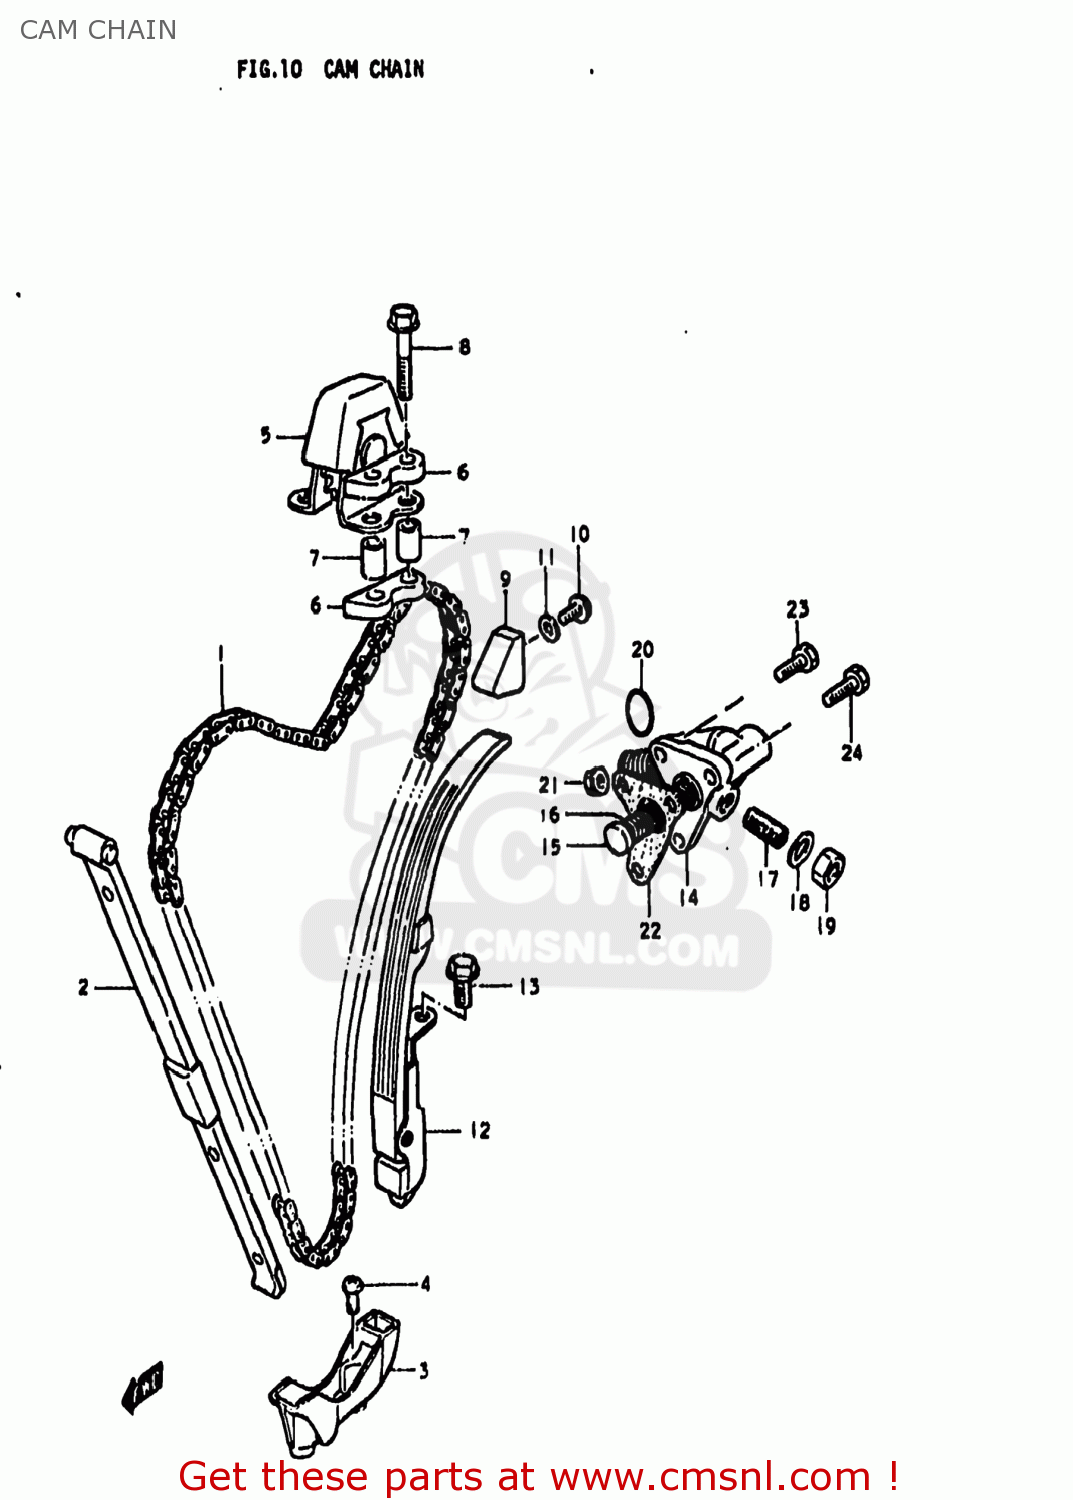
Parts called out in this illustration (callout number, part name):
1	CHAIN,CAMSHAFT DRIVE(120L)
2	GUIDE,CAM CHAIN
3	HOLDER,CAM CHAIN GUIDE
4	SCREW
5	IDLER,CAM CHAIN
6	CUSHION,IDLER
7	SPACER
8	BOLT
9	GUIDE,CAM CHAIN
10	BOLT
11	GASKET (NAS)
12	TENSIONER,CAM CHAIN
13	BOLT
14	ADJUSTER ASSEMBLY,TENSIONER
15	ROD,PUSH
16	SPRING
17	SCREW
18	WASHER
19	NUT
20	O-RING
21	NUT
22	GASKET,TENSIONER ADJUSTER (MCA)
23	SCREW
24	SCREW
